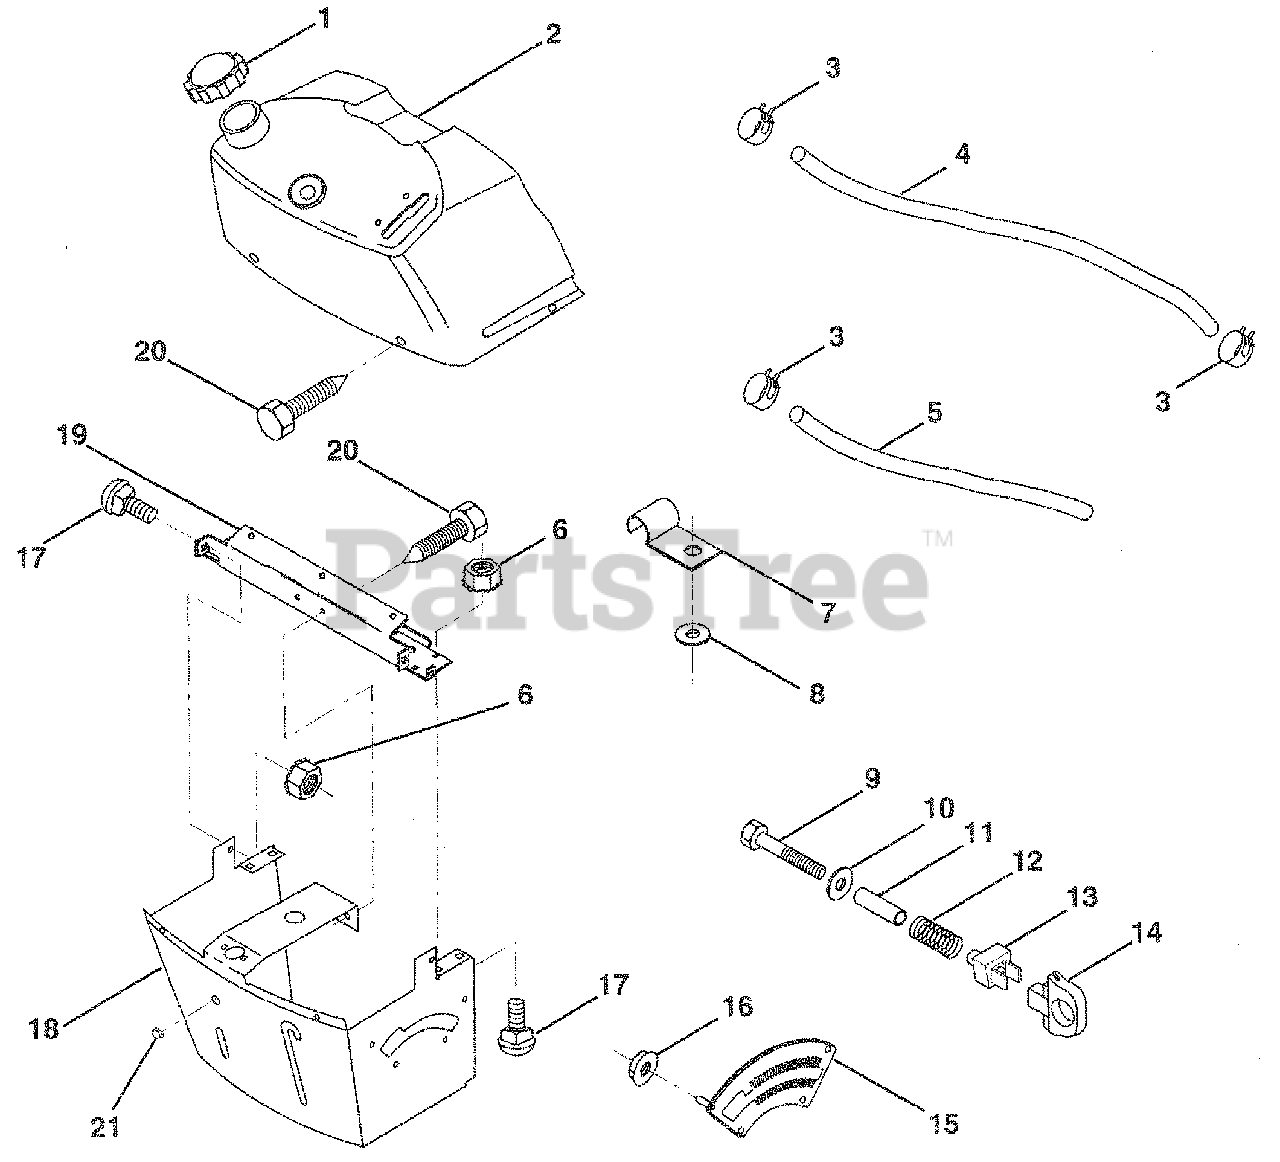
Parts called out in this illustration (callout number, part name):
1	Cap, Fuel
2	Assembly, Dash & Fuel Tank
3	Clamp, Hose
4	Line, Fuel
5	Line, Fuel
6	Nut, Hex, Keps 1/4-20
7	Clip, Fuel Line
8	Washer 9/32 x 3/4 x 16 Ga.
9	Bolt, Hex, Fin 1/4-20 x 1-3/4
10	Washer 11/32 x 11/16 x 16 Ga.
11	Spacer, Split
13	Clip, Height Adjustment
14	Knob, Height Stop
15	Adjustment, Quadrant Height
16	Nut, Self-Threading 3/16-18
17	Bolt, Carriage 1/4 - 20 x 1/2 Gr. 5
18	Support Assembly, Dash
19	Brace, Cross
20	Screw 1/4-20 x 1/2
21	Plug, Dome
